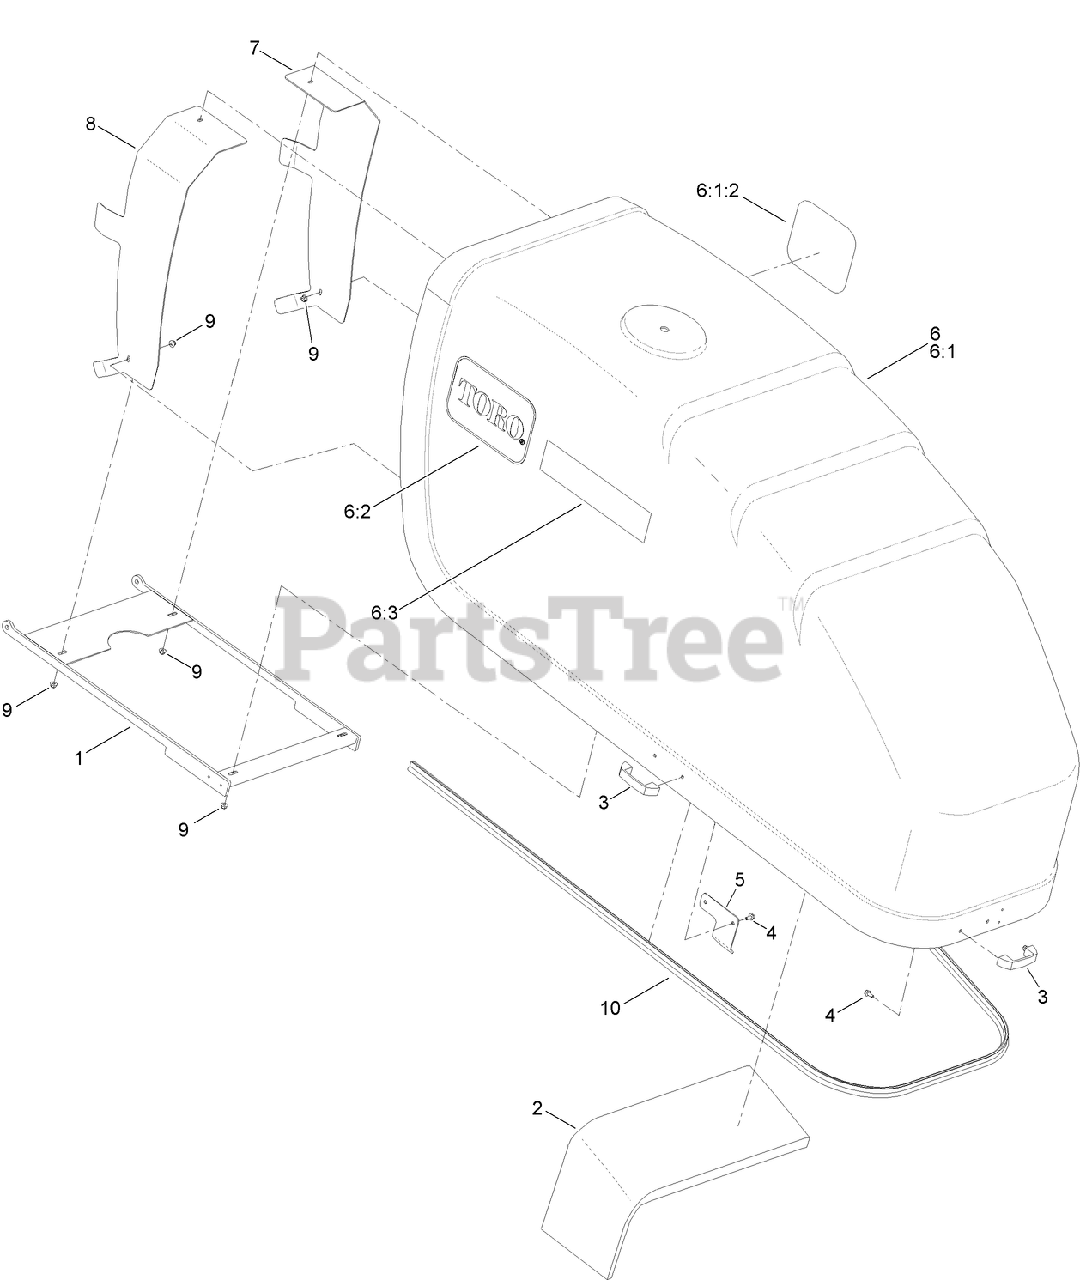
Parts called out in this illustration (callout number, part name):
1	HINGE-HOOD, FRONT
2	FOAM-HOOD, REFLECTIVE
3	HANDLE-GRAB
4	SCREW-HHF
5	GUIDE-HOOD, FRONT
6	FRONT HOOD AND DECAL ASM
6:1	HOOD-FRONT
6:1:2	SCREEN-HOOD, FRONT
7	PLATE-CATCH, HOOD
8	PLATE-CATCH, HOOD
9	NUT-HF, NI
10	SEAL-BULB
